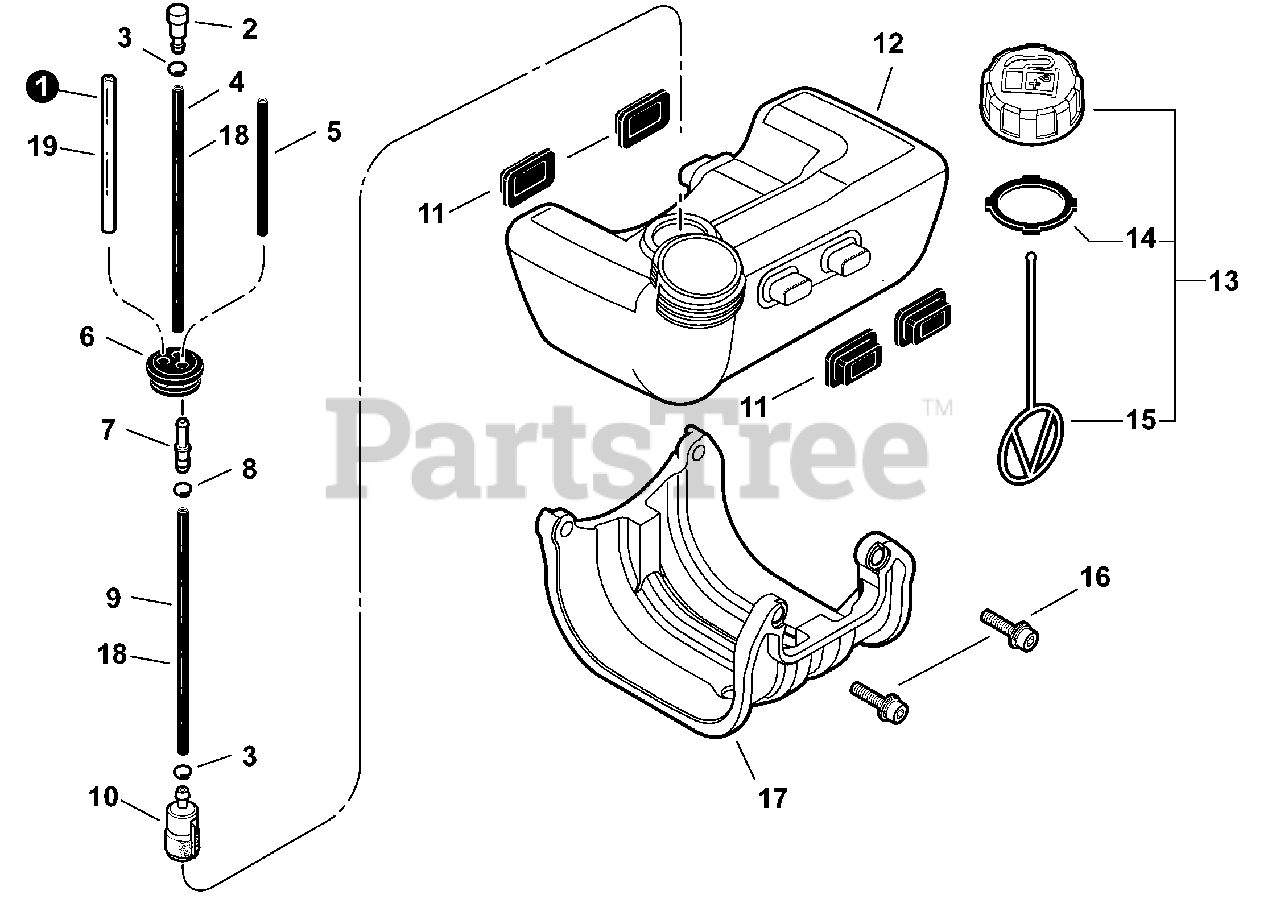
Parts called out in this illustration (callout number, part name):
1	PIPE, FUEL 3×6×80 CLEAR
2	VENT ASSY
4	PIPE 3×6×90mm
5	PIPE, FUEL - 3×5×67 - BLACK
6	GROMMET, FUEL
7	CONNECTOR, PIPE 5×3.5
8	CLIP 6.5MM
9	PIPE, FUEL 3×6×120 BLACK
10	FILTER, FUEL
11	CUSHION, FUEL TANK
12	TANK, FUEL
13	CAP ASSY, FUEL
14	GASKET, FUEL CAP
15	CONNECTOR, CAP L= 123
16	BOLT M5×20
17	GUARD, PLASTIC FUEL TANK
18	PIPE, BULK - 3×6mm BLACK
19	PIPE, BULK - 3×6mm CLEAR
